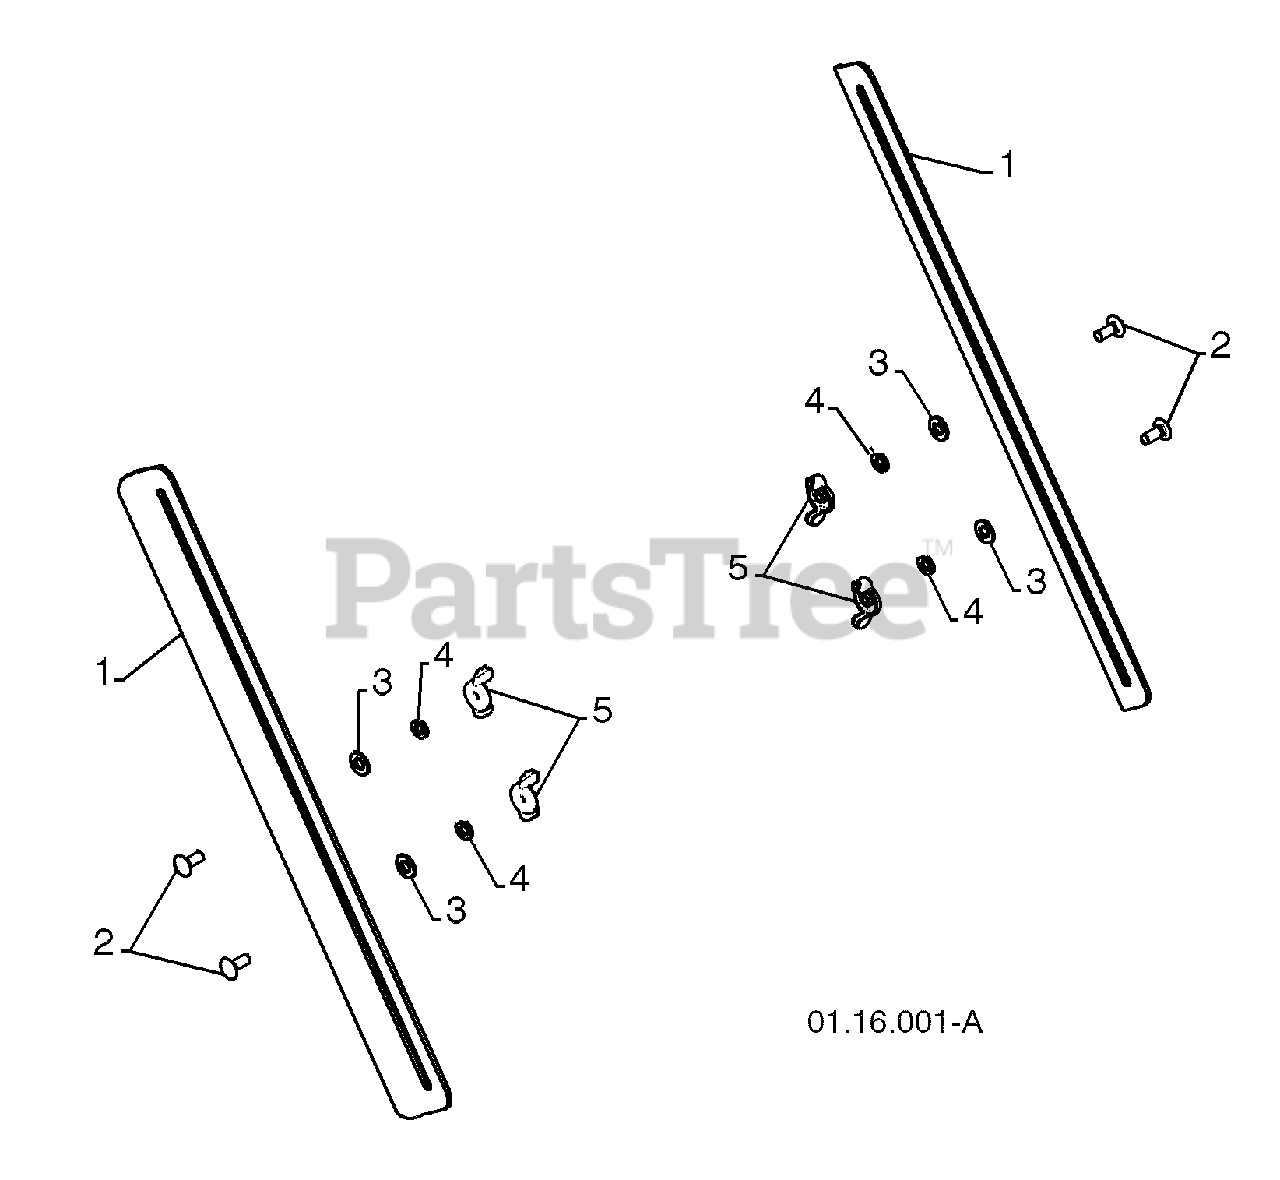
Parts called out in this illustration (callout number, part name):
1	DRIFT CUTTER BAR
2	CARRIAGE BOLT 5/16-18 X .750
3	PLASTIC WASHER
4	LOCKWASHER 5/16
5	NUT 5/16-18
